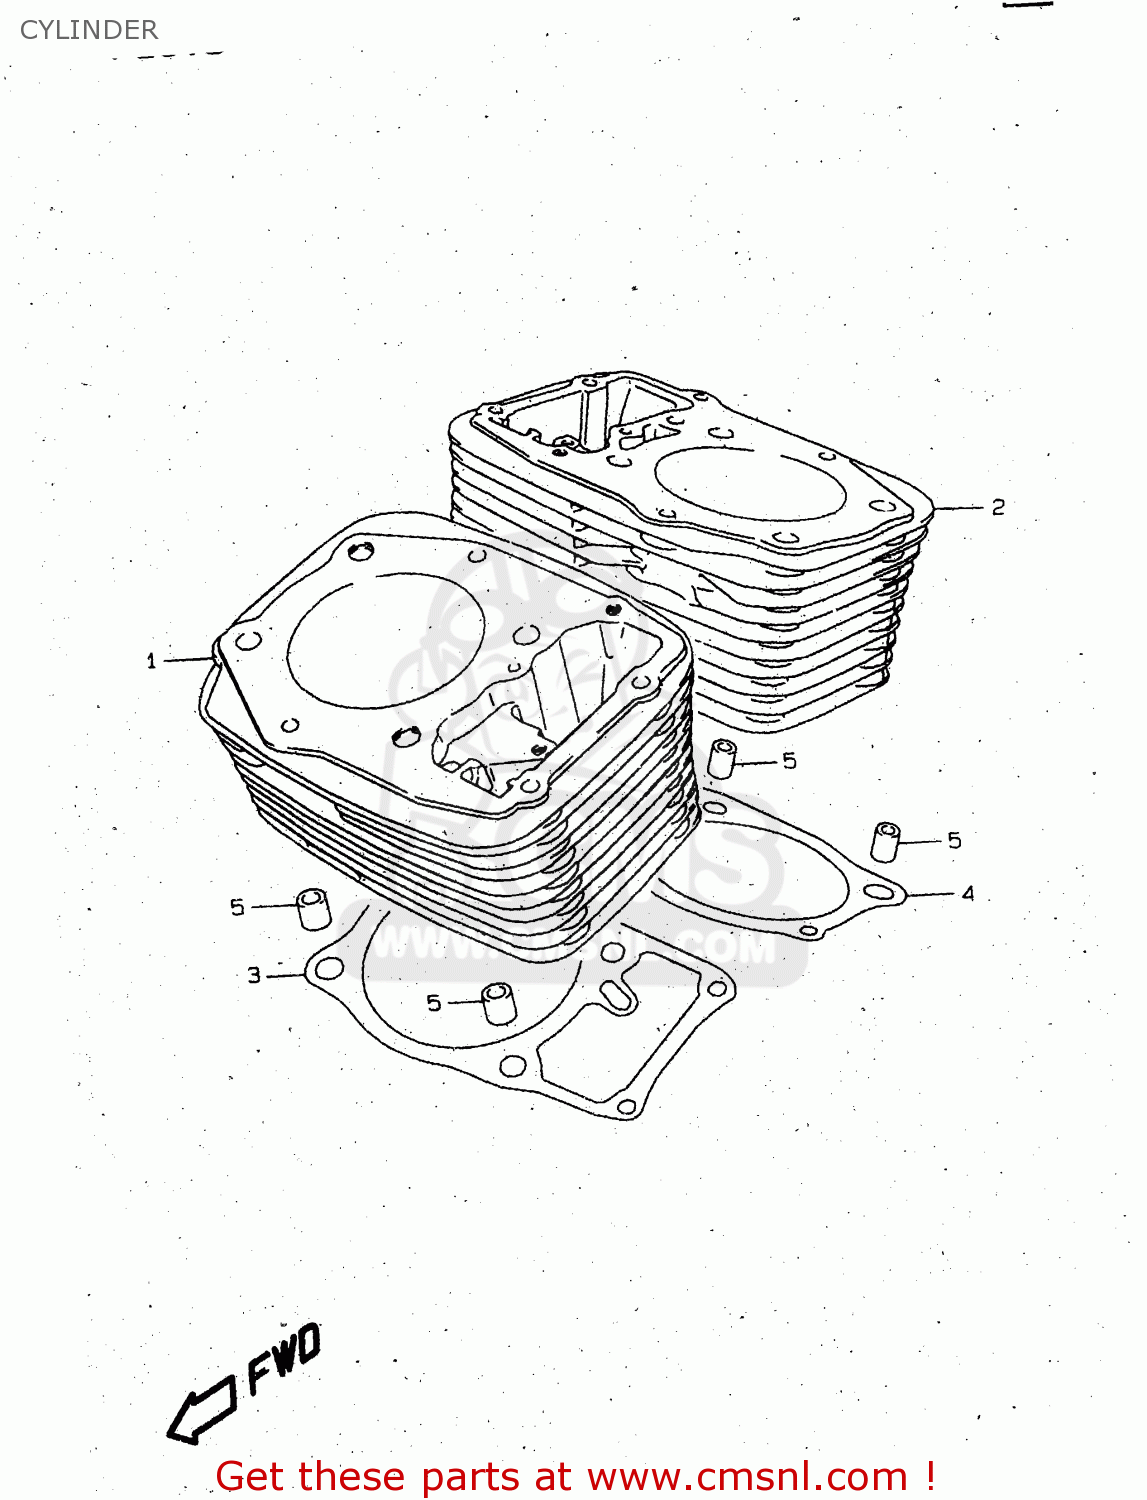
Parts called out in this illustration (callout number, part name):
1	CYLINDER,FRONT
2	CYLINDER,REAR
3	GASKET,CYLINDER FR (NAS)
4	GASKET,CYLINDER RR (NAS)
5	PIN
